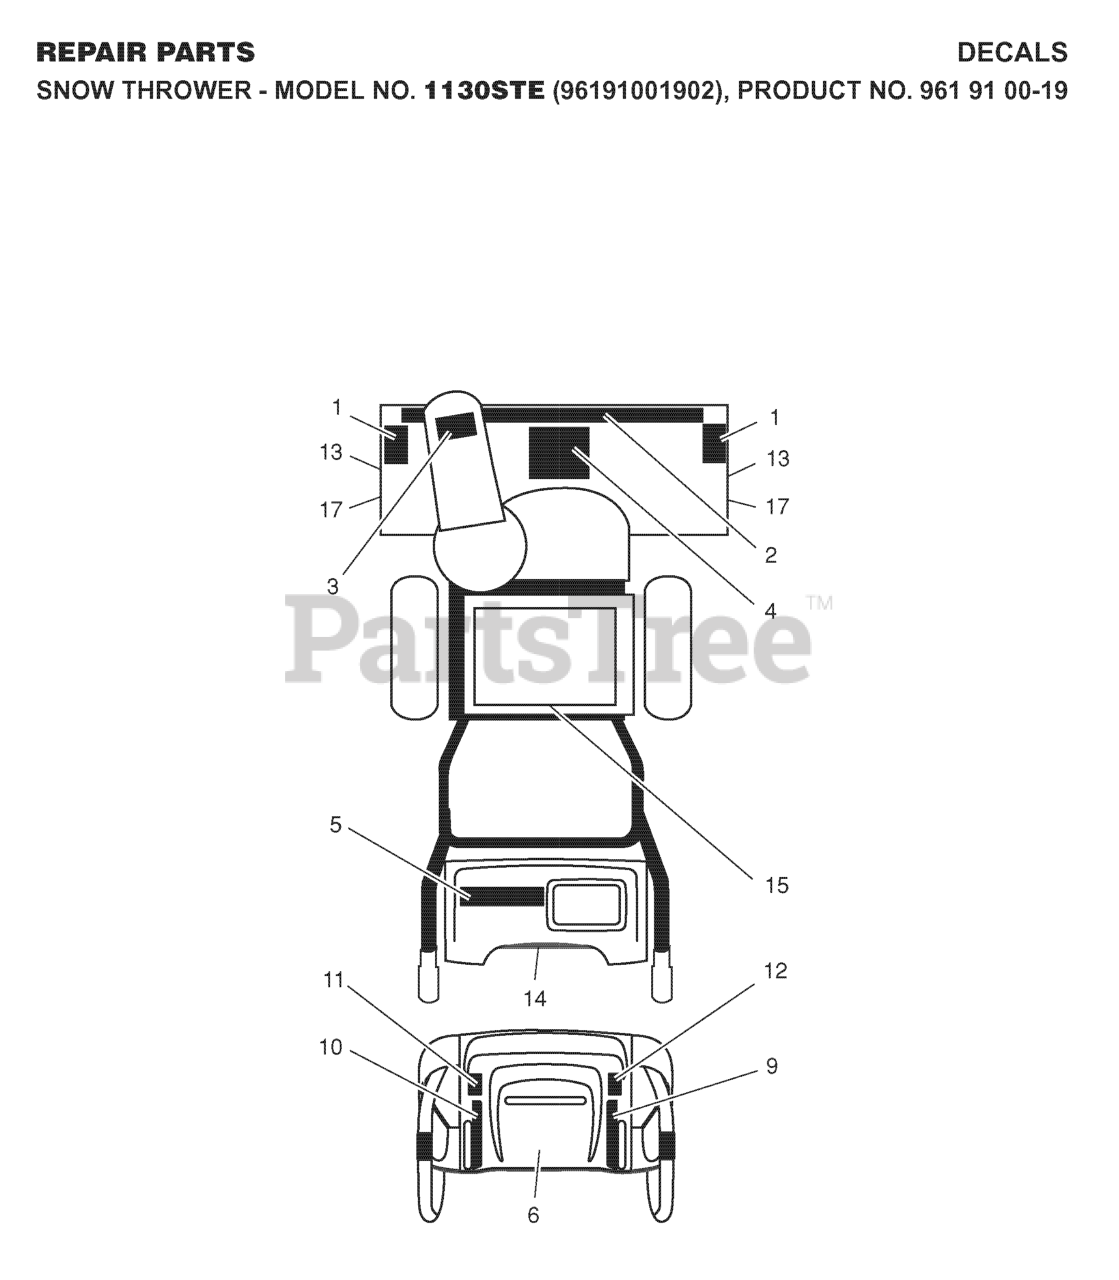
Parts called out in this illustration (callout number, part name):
1	DECAL.AUGER.SAFETY.
3	DECAL.CHUTE.SAFETY.
4	DECAL.AUGER."
6	DECAL.CONSOLE.INSTRUCTION
10	DECAL.REM.DEFLECTOR.LT
11	DECAL.POWER.STEER.LT.TRIG.INT
12	DECAL.POWER.STEER.RT.TRIG.INT
14	DECAL.FENDER
15	DECAL.BELT.GUARD.
17	DECAL, HUSQVARNA
